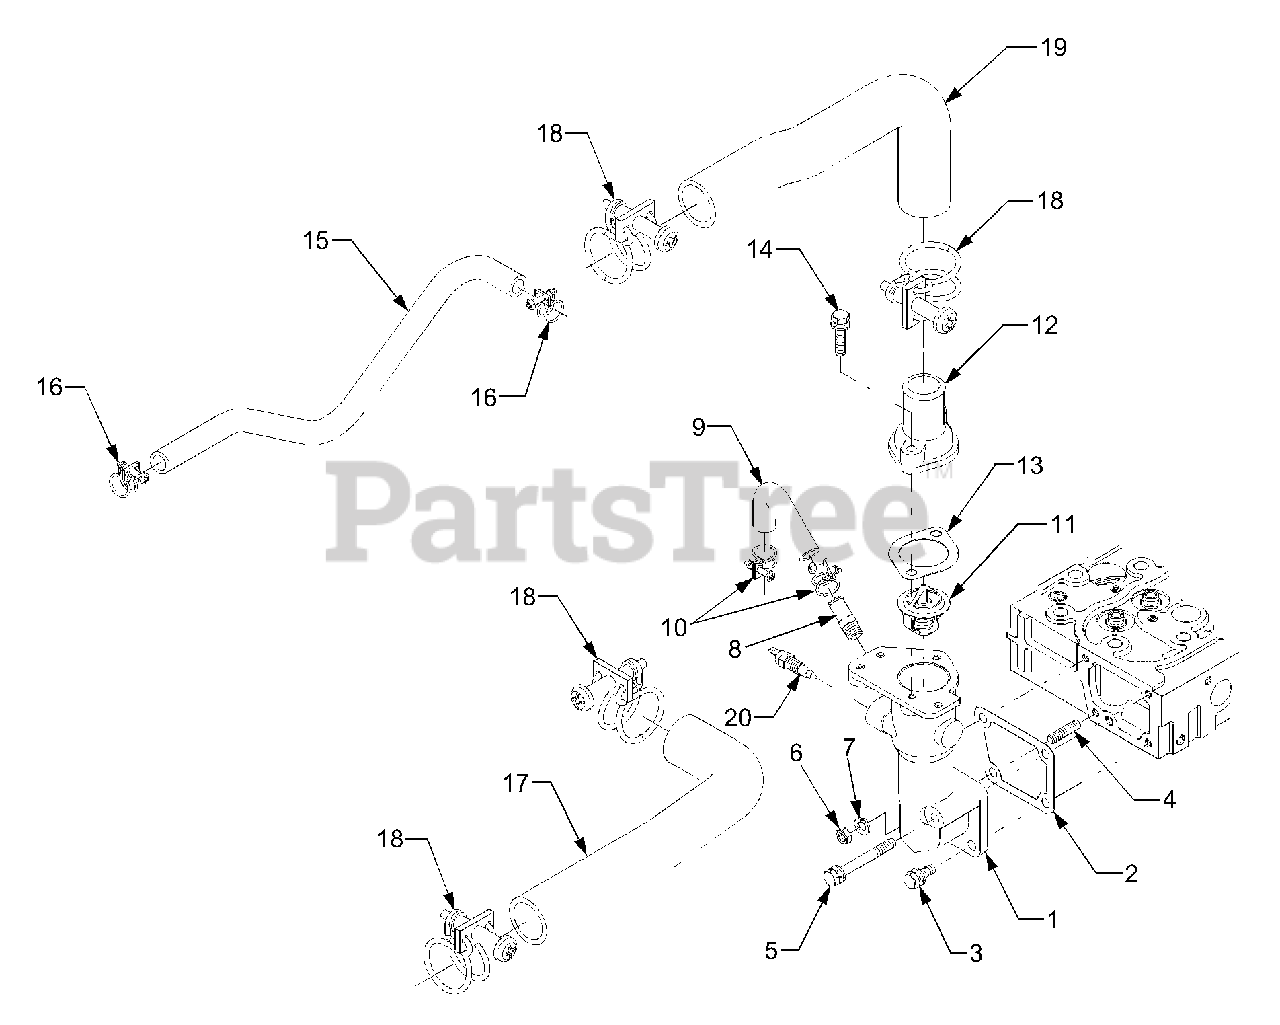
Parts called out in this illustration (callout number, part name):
1	Flange, Water
2	Gasket, Flange
7	Washer, Spring
8	Pipe, Water Return
11	Thermostat Ass'y
12	Cover, Thermostat
13	Gasket
15	Pipe, Water Return
17	Pipe, Water Lower
19	Pipe, Water Upper
20	Switch, Thermo Water
